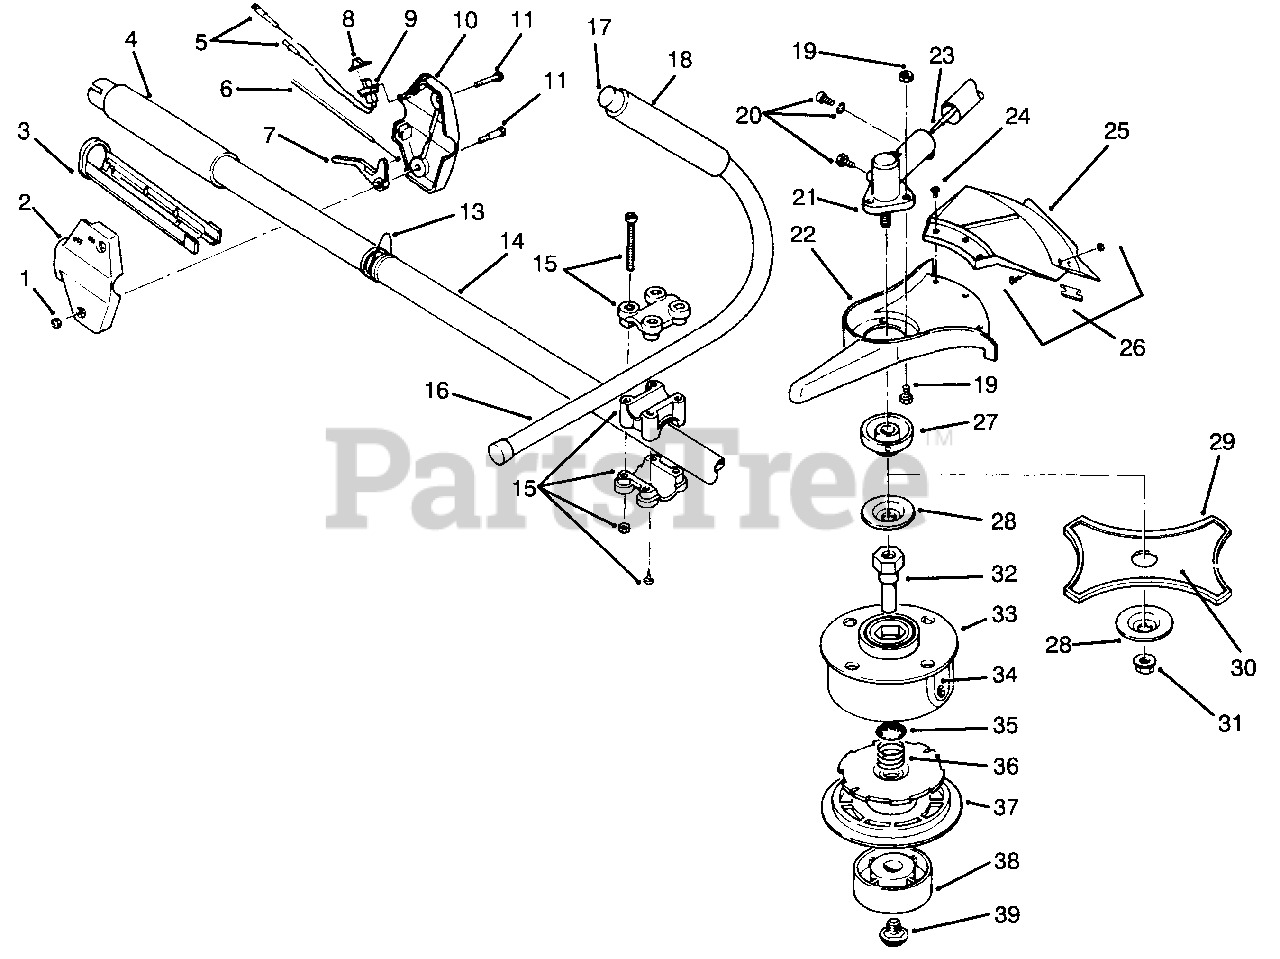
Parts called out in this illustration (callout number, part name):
1	Nut-Lock
2	Housing-R.H.
5	Assembly-Lead Wire
6	Cable-Throttle
7	Lever-Throttle
8	Cap-Switch
10	Housing-L.H.
11	Screw-Hex. Hd.
13	Clamp-Shoulder Strap
14	Assembly-Upper Drive
15	Assy.-Bracket, Handle (Incl. 4 Screws & 4 Nuts)
16	Assy.-J-Handle (Incl. Ref. No.17 & 18)
17	Closure-Tube
19	Guard Mount Screws & Nuts
20	Mount Hardware & Plug
21	Assembly-Gear Box (Incl. Ref. No. 27 & 28)
22	Mount-Guard
23	Shaft-Flexible Drive
24	Screws-Guard Mount
25	Assy.-Guard & Blade (Incl. Ref. #26)
26	Assembly-Blade (Incl. 2 Screws & 2 Nuts)
27	Driver-Blade
28	Washer-Lower Retaining
29	Cover-Blade
30	Blade (Incl. Ref. No.29)
31	Nut-Lock
32	Shaft-Spool
33	Assy.-Outer Spool & Eyelet
35	Retainer (10 Pack)
37	Reel-Inner
38	Assy.-Bump Head Knob
39	Bolt-Bump Head
